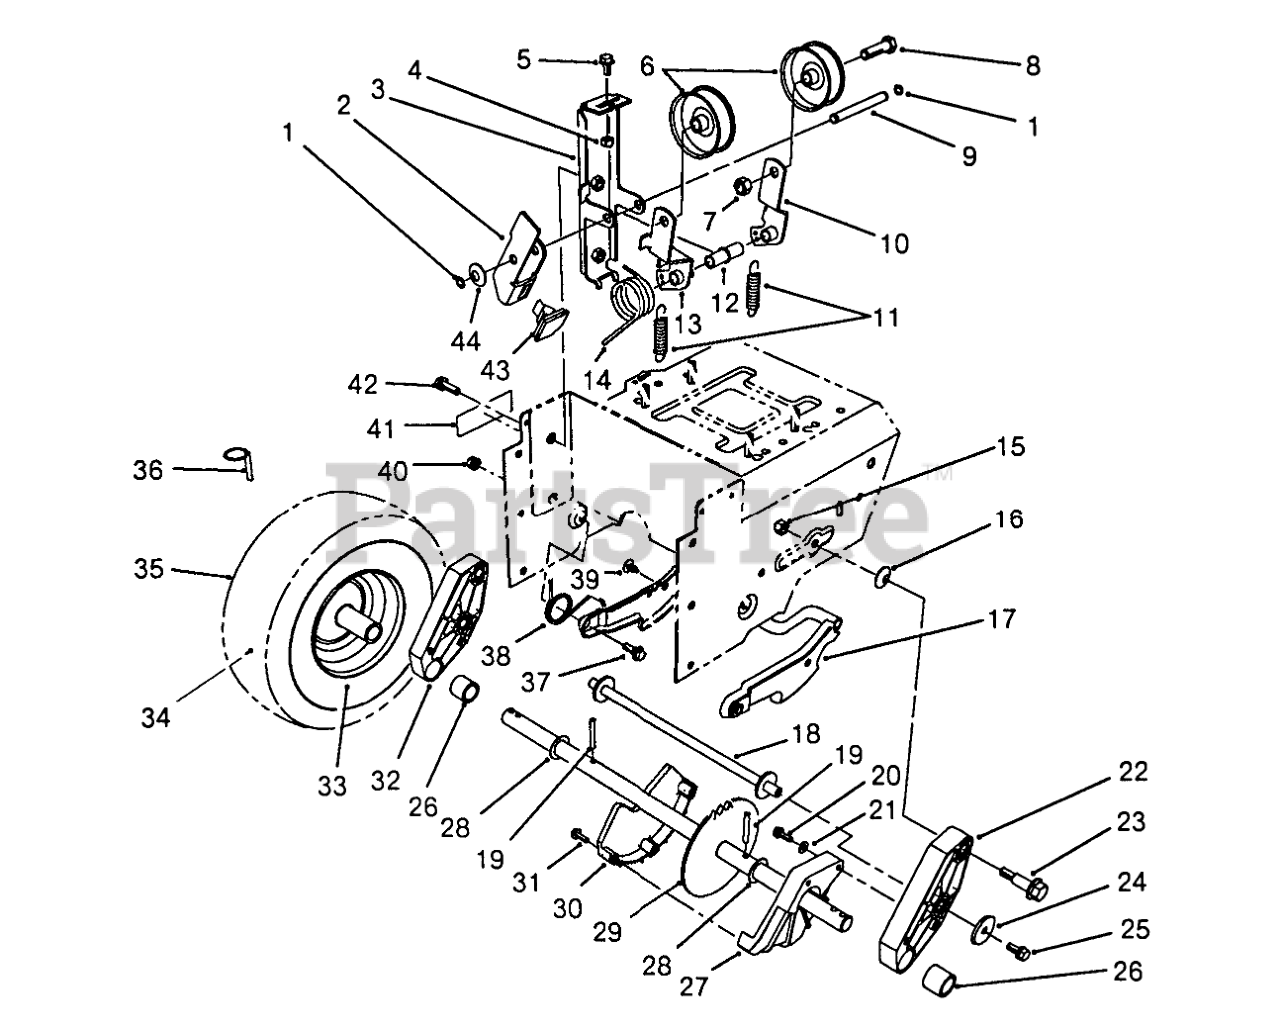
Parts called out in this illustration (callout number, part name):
1	RING-RETAINING
2	ARM-BRAKE
3	IDLER ARM BRACKET ASM
4	NUT-LOCK, NI
5	SCREW-HHF
6	PULLEY-IDLER
7	NUT-LOCK, NI
8	SCREW-HH
9	PIN-IDLER
10	ARM-IDLER, TRACTION
11	SPRING-EXTENSION
12	BUSHING-IDLER
13	ARM-IDLER, IMPELLER
14	TORSION SPRING
15	NUT-LOCK, NI
16	WASHER-SPRING
17	Latch-Arm
18	PIVOT TUBE WA
19	PIN-ROLL, SLOTTED
20	SCREW-HWH
21	WASHER-FLAT
22	Pivot Arm Assembly L.H. (Incl. Ref. # 26)
23	BOLT-SHOULDER
24	WASHER
25	SCREW-TAPTITE
26	BUSHING-AXLE
27	GUARD-CHAIN, LH
28	WASHER-THRUST
30	GUARD-CHAIN, RH
32	Pivot Arm Assembly R.H. (Incl. Ref. #26)
33	WHEEL RIM
34	INNER TUBE
36	PIN-LYNCH
37	SCREW-SHOULDER
38	SPRING-LATCH, TORSION
39	FASTENER-PANEL
40	NUT-LOCK, NI
41	DECAL-WARNING
42	SCREW-HHF
43	Brake Pad
44	WASHER-CURVED
